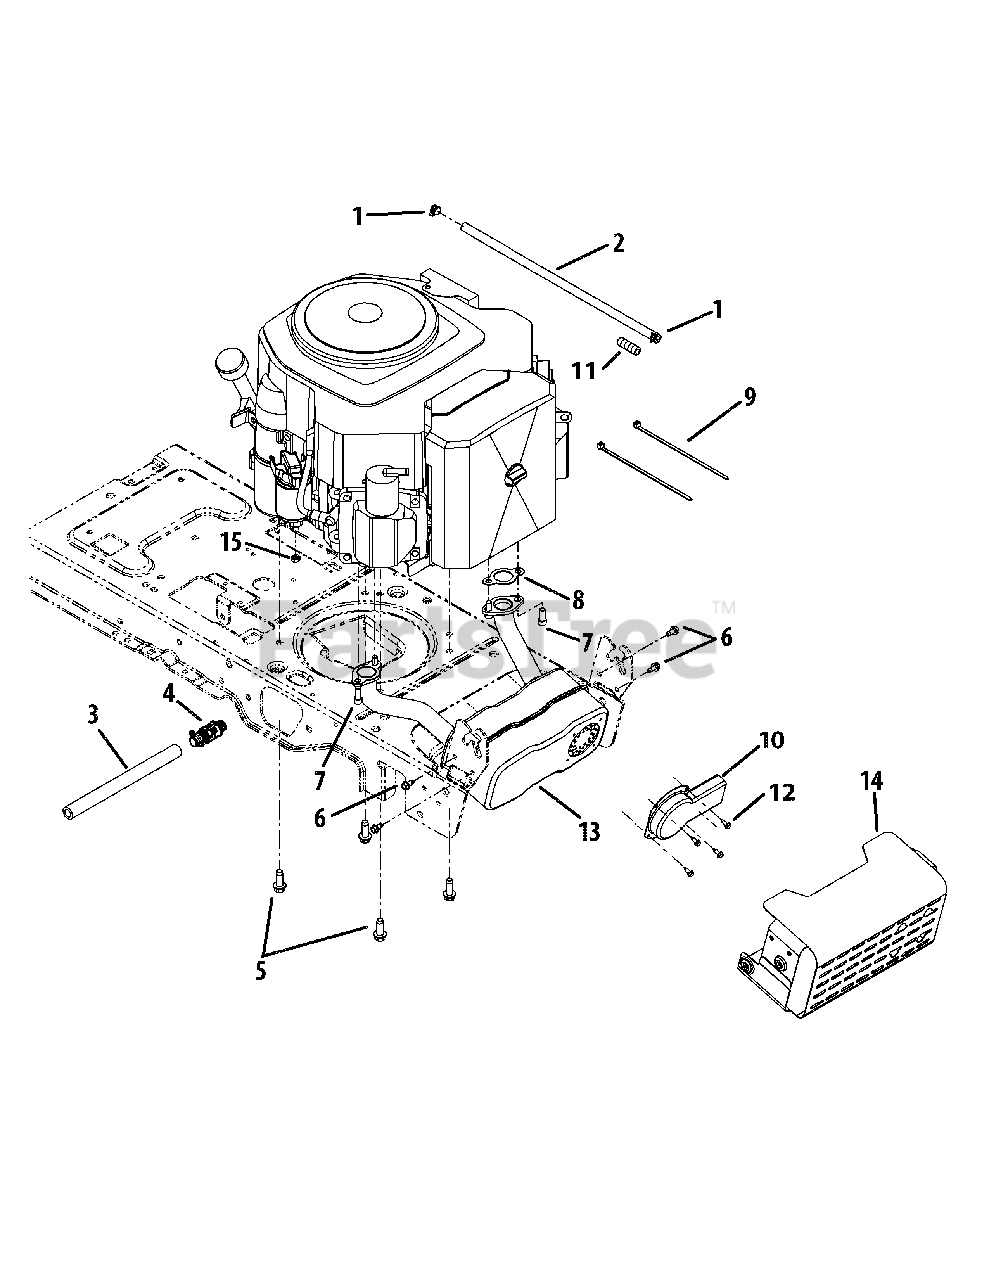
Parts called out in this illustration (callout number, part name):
1	Hose Clamp
2	Fuel Line
3	Oil Drain Hose
4	Oil Drain
5	TT Screw 3/8-16 x 1.00
6	Hex Wash S-Tapp Screw 1/4-20 x .50
7	Screw. 5/16-18 x .75
8	Exhaust Gasket
9	Cable Tie
10	Long Muffler Deflector
11	Vent Hose
12	Hex AB Screw #8-18 x .50
13	Muffler
14	Muffler Shield Assembly
15	Sems Nut 1/4-20
